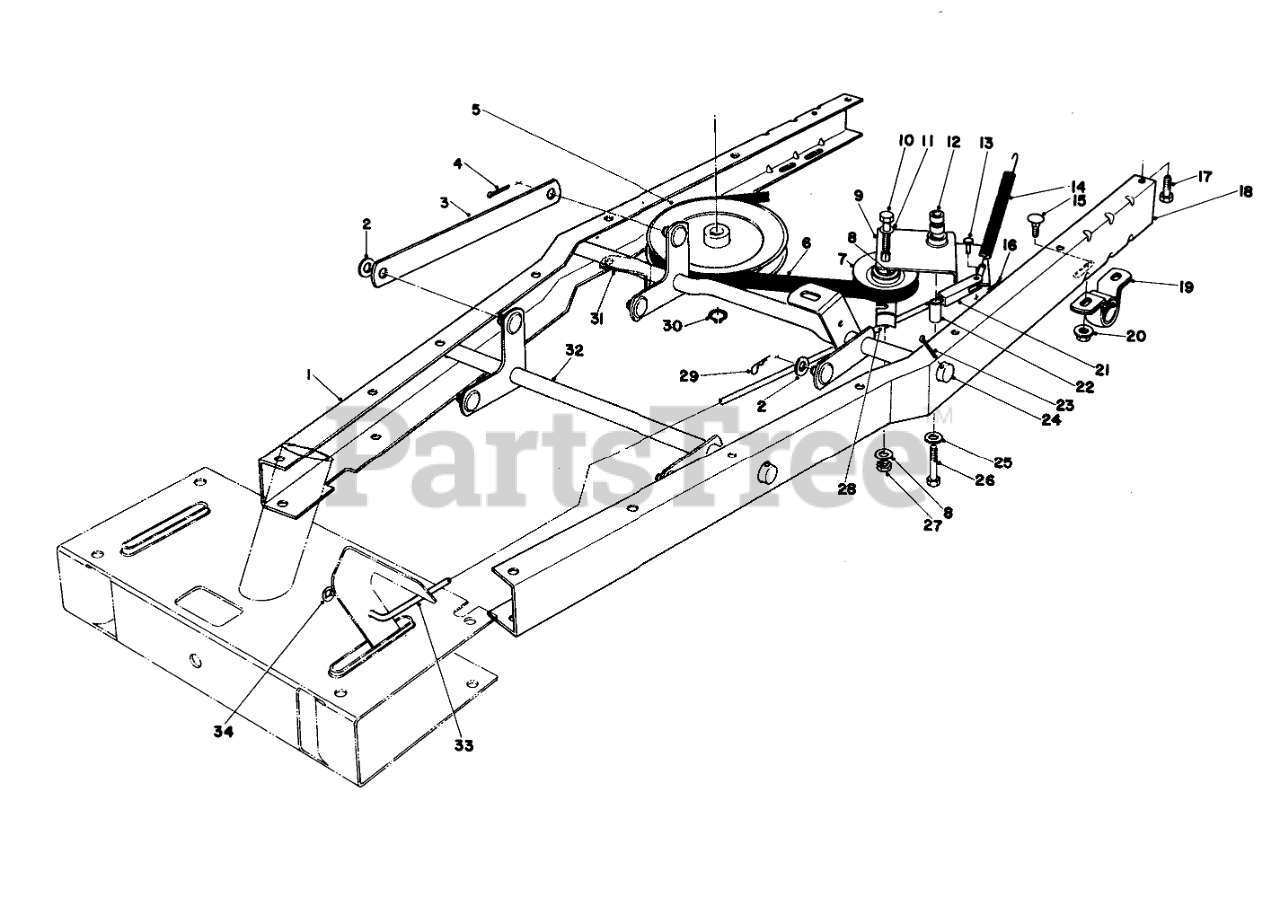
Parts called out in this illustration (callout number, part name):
1	Frame-Channel R.H.
2	WASHER-FLAT
3	Linkage-Height Adj.
4	PIN-COTTER
5	PULLEY
6	V-BELT
7	PULLEY-IDLER
8	WASHER-FLAT
9	Traction Idler (Incl. Ref. #12)
10	SCREW-HH
11	WASHER-FLAT
12	Bushing
13	PIN-CLEVIS
14	Clutch Tension Spring
15	SCREW-CARR
16	PIN-COTTER
17	SCREW-HH
18	LH FRAME CHANNEL B
19	PILLOW BLOCK
20	NUT-HF
22	PIVOT SPACER
23	Cotter Pin
24	REAR HT ADJ WA B
25	WASHER-PLAIN
26	SCREW-HH
27	NUT-LOCK, SIDE
28	RETAINER-BELT
29	PIN-COTTER
30	RING-SNAP, EXTERNAL
31	TRANS BELT RET B
32	FRONT LIFT WA B
33	Clutch Rod
34	PUSH ON SPEED NUT 1/4
